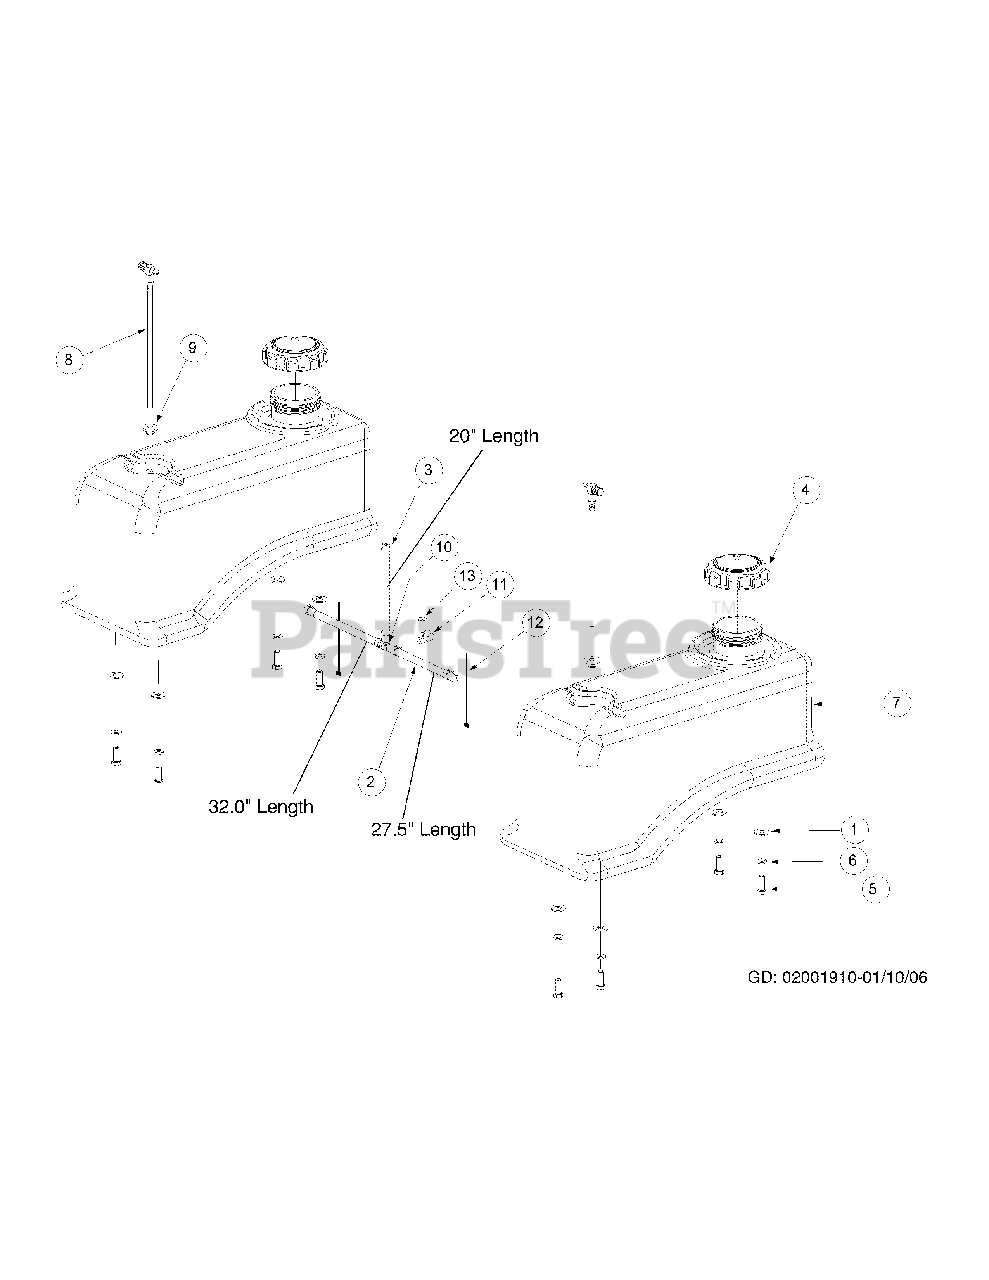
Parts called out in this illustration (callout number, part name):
1	Flat Washer, .406 ID, 1.0 OD, .105
2	Hose, 1/4" Fuel Line (79.5 inches)
3	Clamp, Union
4	Fuel Cap, 3.5
5	Hex, Cap Screw, 3/8-16, .88
6	Lock Washer, 3/8
7	Fuel Tank
8	Fuel Fitting
9	Fuel Tank Grommet
10	Tee Fitting, Fuel
12	Cable Tie
13	Flatwasher 1/4 x .630 x .0515
